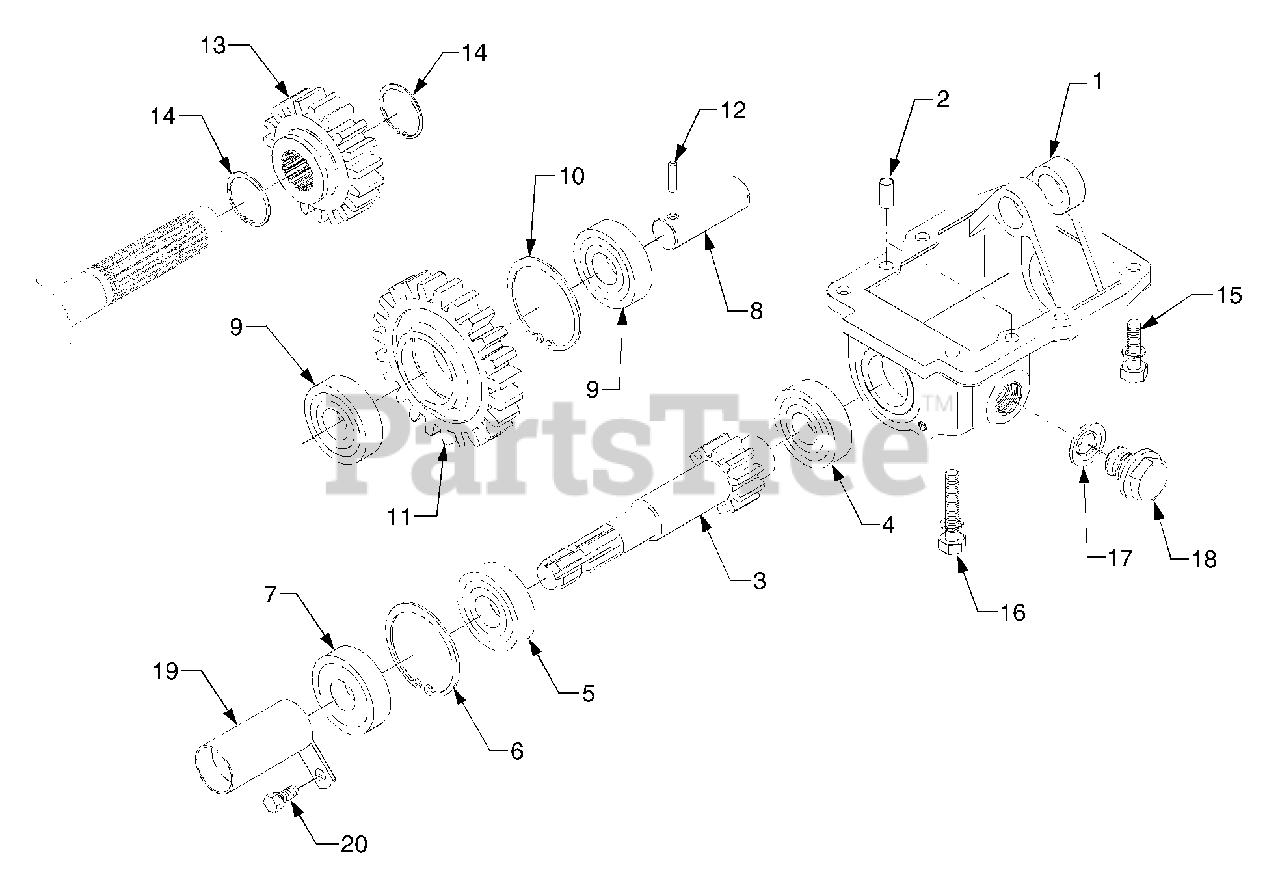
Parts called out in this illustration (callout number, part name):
1	Case, Mid PTO
2	Pin, Straight
3	Shaft, 14 Gear (M. PTO)
4	Bearing, Ball
5	Bearing, Ball
8	Shaft, Counter (M. PTO)
9	Bearing, Ball
11	Gear, 41 Spur
13	Gear, 20 Spur
18	Plug, Drain
19	Cover, Protect
